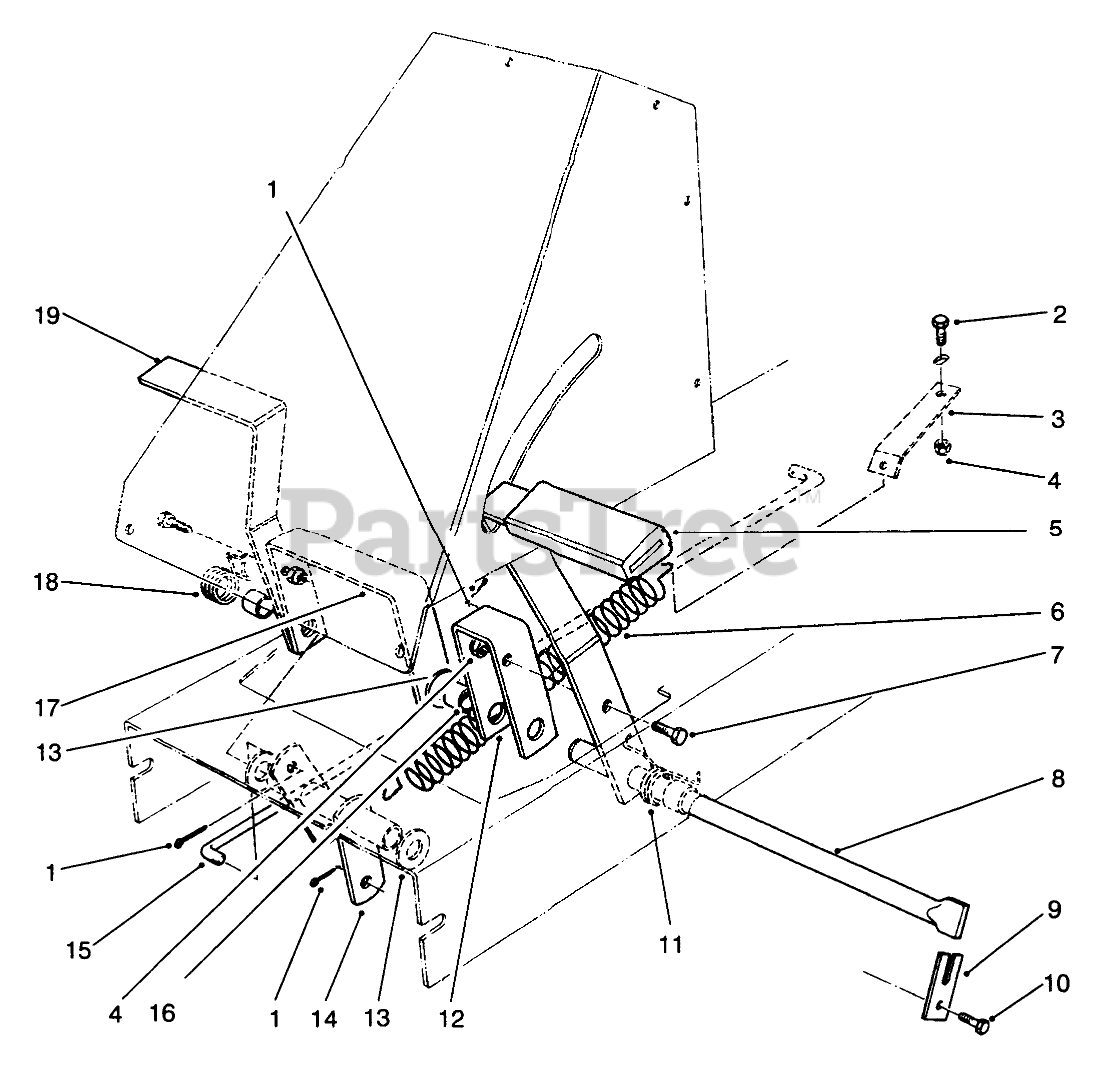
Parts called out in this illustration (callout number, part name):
1	PIN-COTTER
2	SCREW-HH
3	BRKT-SPRING RET
4	NUT-LOCK, NI
5	PAD-PEDAL
6	SPRING-EXTENSION
7	SCREW-HH
8	SHAFT-PEDAL PIVOT
9	RETAINER-SHAFT
10	SCREW-HH
11	SPRING-TORS CLUTCH
12	Bracket-Clutch Pedal
13	WASHER-FLAT
14	Pivot Tube
15	ROD-ENGAGE
16	SPACER-PEDAL
17	Bracket-Brake Pedal
18	SPRING-TORS BRAKE
19	Pedal
